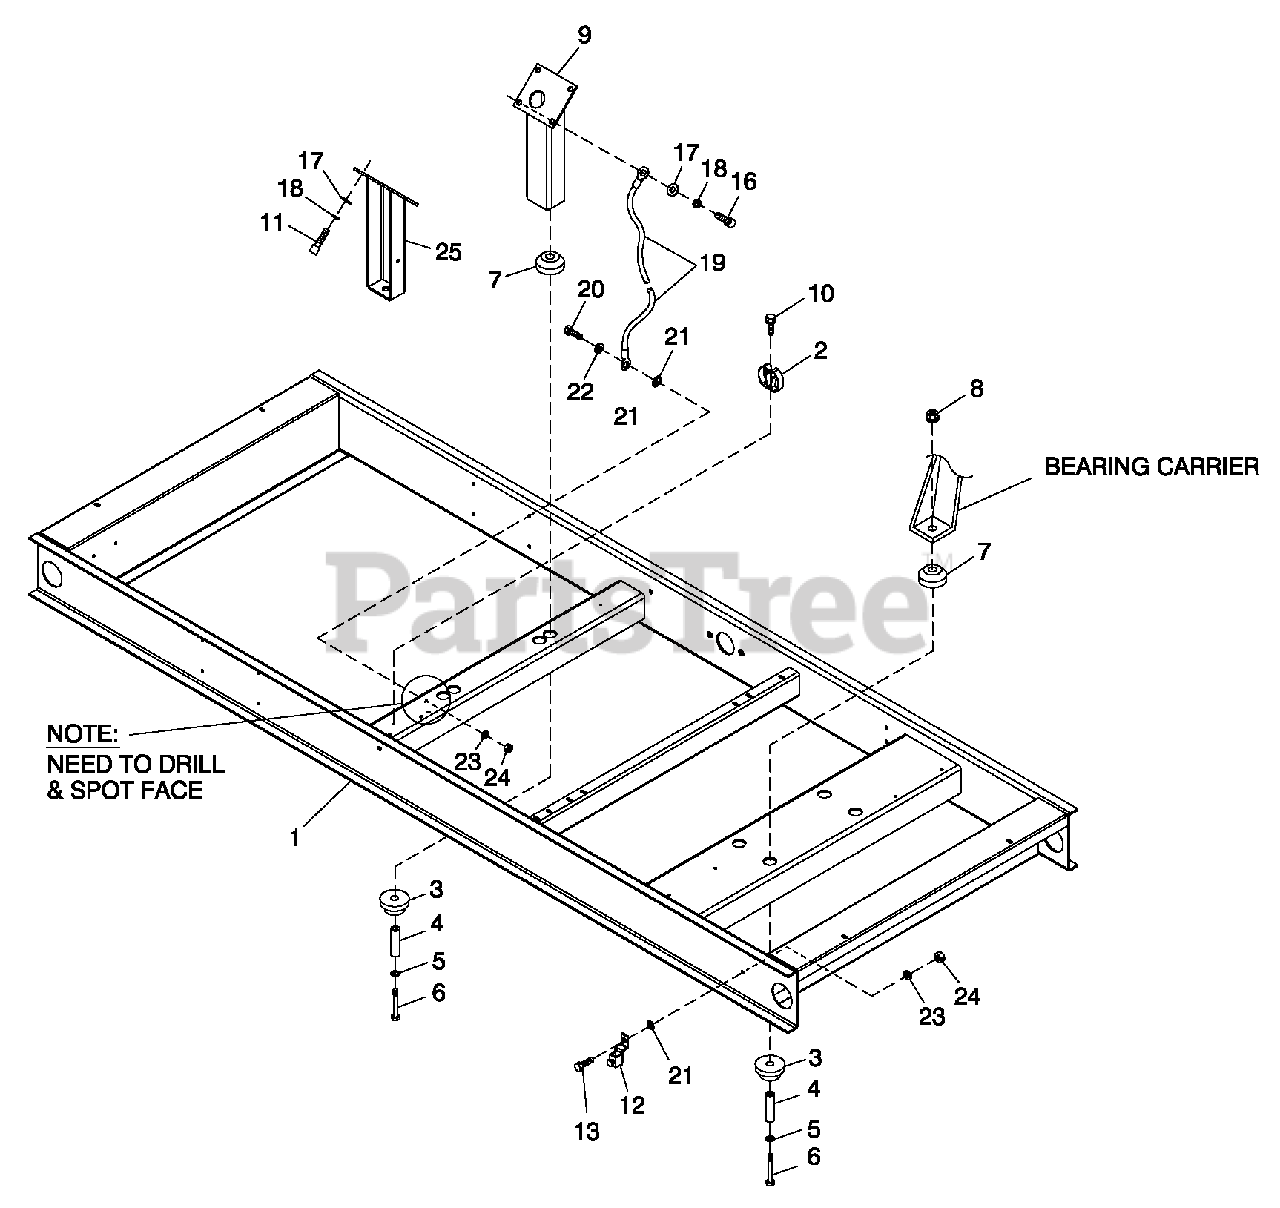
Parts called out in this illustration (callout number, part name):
1	BASE CP 6.8L70KW/5.4L 55KW DD
2	SPRING CLIP HOLDER .37-.62
3	DAMPENER VIBRATION
4	SPACER .49 X .62 X 1.87 PWDR/ZINC
5	WASHER FLAT M12
6	SCREW HHC M12-1.75 X 85 G8.8
7	DAMPENER VIBRATION 50 WHITE
8	NUT LOCKING M12-1.75
9	SUPPORT ENG 5.4L LH/RH 6.8L RH
10	SCREW HHTT M4-0.7 X 8 BP
11	SCREW SHC M10-1.5 X 30 G12.9 (5.4L)
12	LUG SOLDERLESS 3/0-#4 X 13/32 CU
13	SCREW HHC M8-1.25X 25 G8.8
16	SCREW SHC M10-1.5 X 30 G12.9
17	WASHER FLAT 3/8-M10 ZINC
18	WASHER LOCK M10
19	ASSY WIRE 14.00"
20	SCREW HHC M8-1.25X 30 G8.8
21	WASHER SHAKEPROOF INT 3/8
22	WASHER LOCK M8-5/16
23	WASHER FLAT 5/16-M8 ZINC
24	NUT HEX M8-1.25G8YEL CHR
25	SUPPORT, ENGINE (6.8L LH SIDE)
